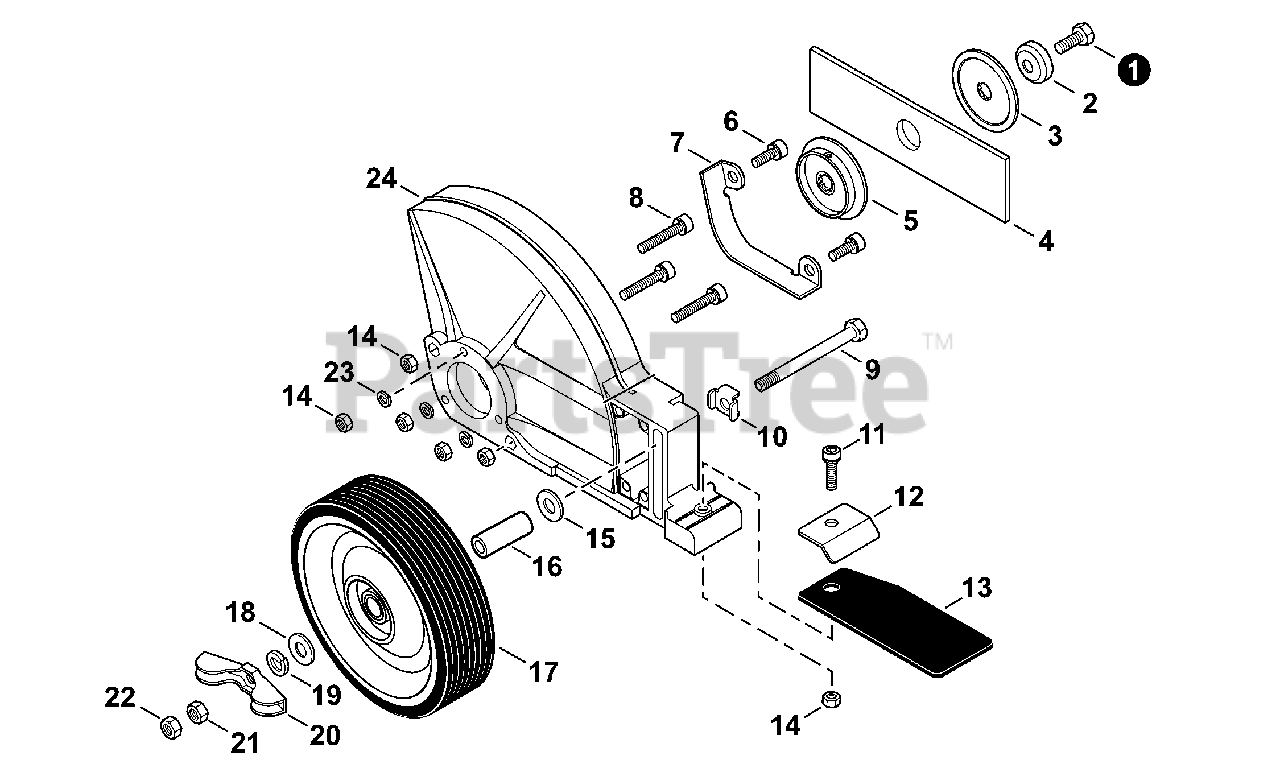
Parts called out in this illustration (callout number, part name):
2	GUARD, BOLT
3	PLATE, ADAPTOR - LOWER
4	BLADE - 2 PK
5	PLATE, ADAPTOR - UPPER
6	BOLT M5×12
7	PROTECTOR, GEAR CASE
8	BOLT M5×25
9	BOLT M8×90
10	PLATE, LOCK
11	BOLT 5×16
12	PLATE, FLAP
13	FLAP, DEBRIS
14	NUT - 5
17	WHEEL
19	WASHER, SPRING 8 MM
20	KNOB, FASTENER
22	NUT, LOCK M8
23	WASHER, SPRING 5 MM
24	SHIELD, BLADE
